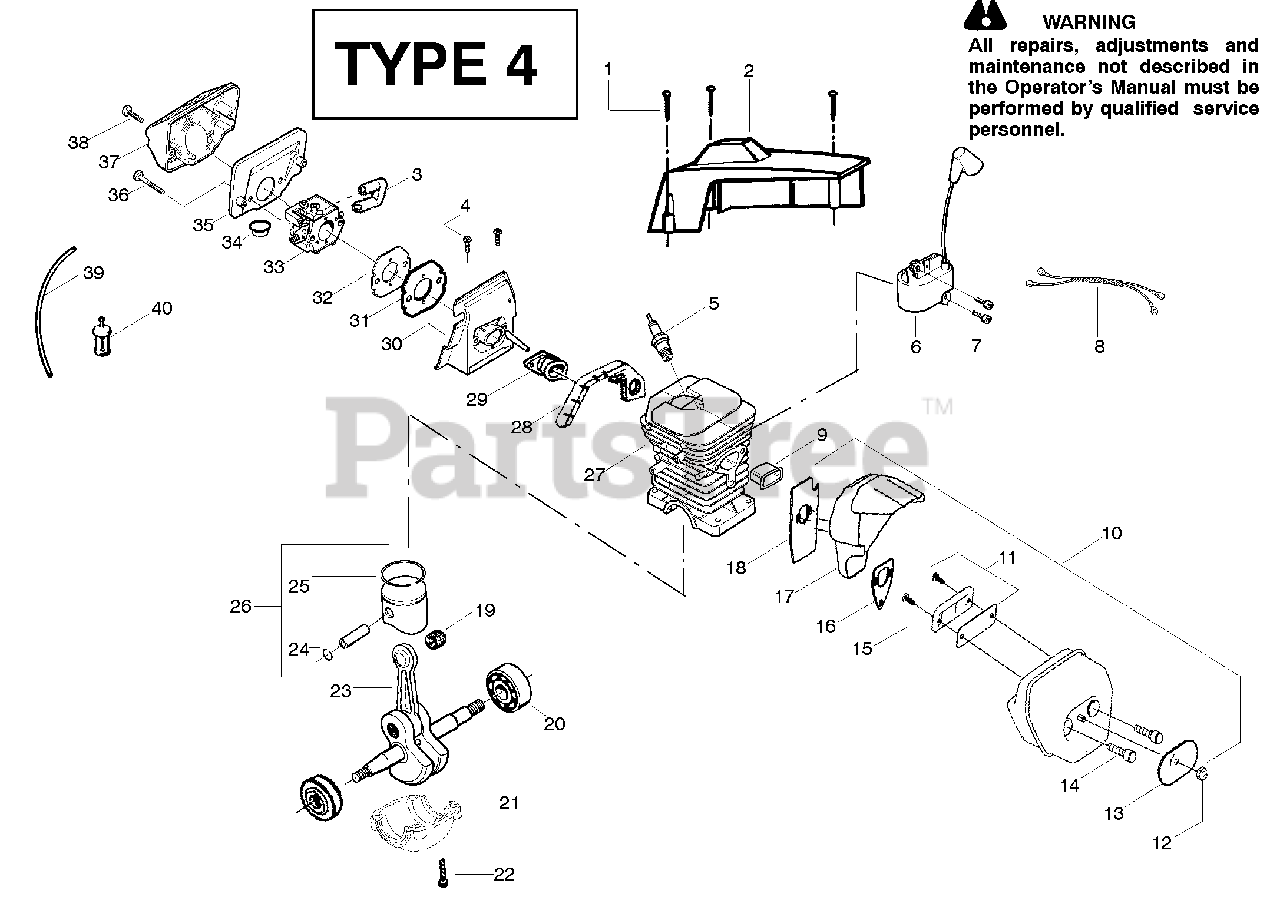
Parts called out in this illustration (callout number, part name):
2	Kit-Cylinder Shield
3	Grommet -Carb.
5	Spark Plug (RCJ-7Y)
6	Module-Ignition
8	Assy-Switch Wire
9	Insulator-Heat
10	Kit-Muffler
11	Kit-Spark Arrestor
12	Nut-Brass
15	Screw-Spark Screen
16	Gasket-Muffler
17	Assy-Muffler Backplate
18	Backplate - Alum.
19	Bearing-Piston Pin
20	Assy-Bearing & Seal
21	Cap-Crankcase
23	Assy-C’shaft & Rod
24	Retainer-Piston Pin
26	Kit-Piston
27	Assy-Cyl/Crankcase
28	Seal-Super Clean
30	Adapter-Carb.
31	Intake Plate-Carb
33	Kit-Carburetor (WT-657)
35	Filter-Air (Bottom)
37	Filter-Air (Top)
39	Kit-Fuel Line (Small)
40	Assy-Fuel Pick-up
